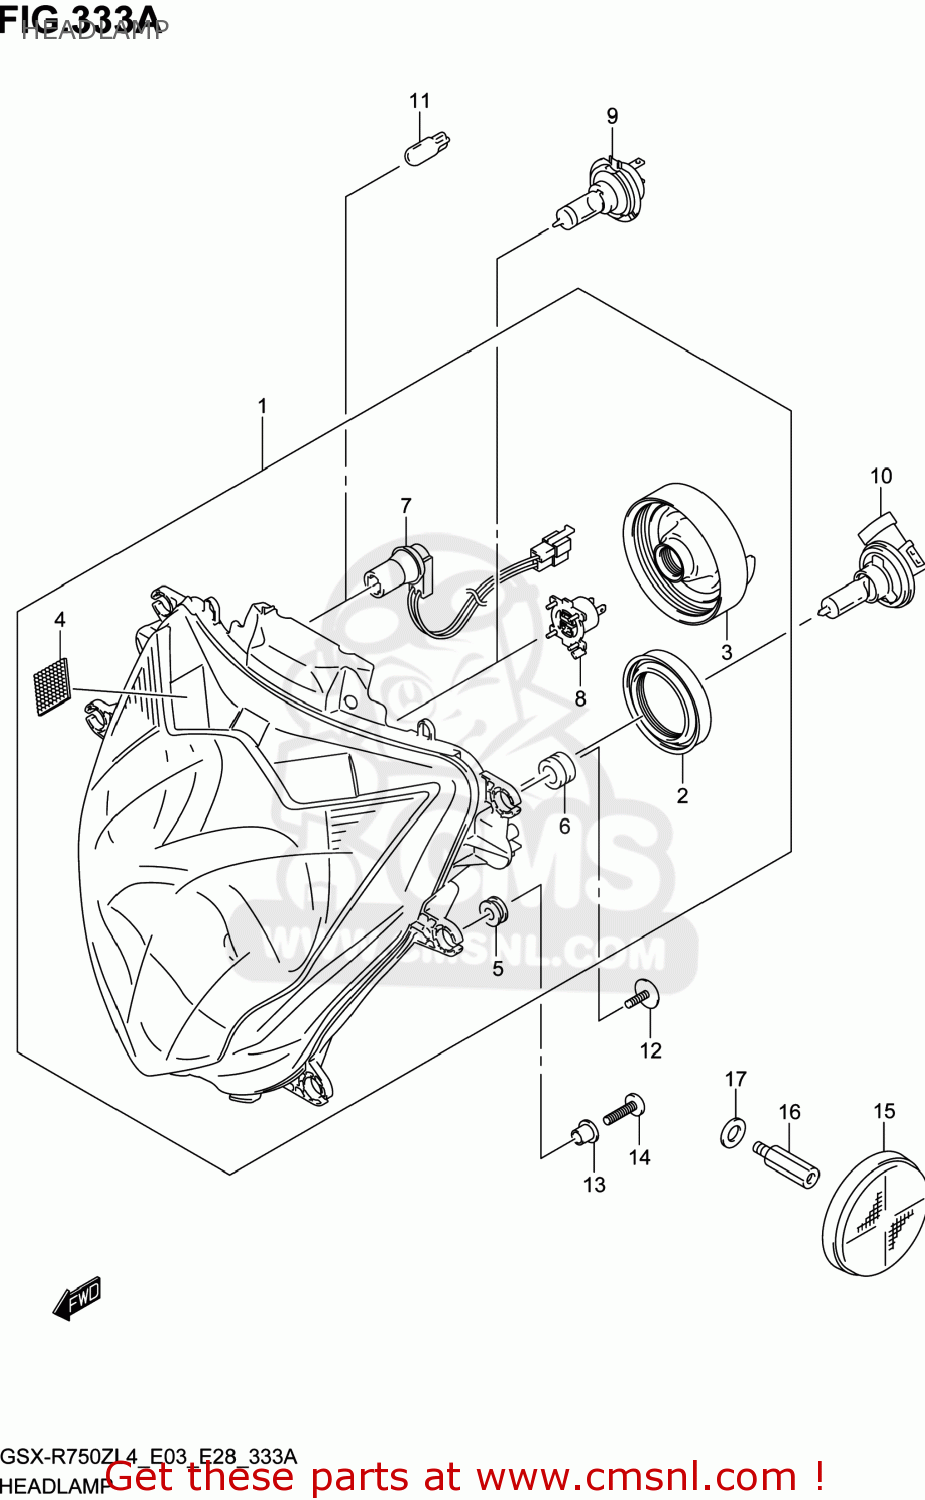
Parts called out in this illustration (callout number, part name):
1	HEADLAMP ASSY
2	COVER,SOCKET
3	COVER,SOCKET
4	FASTENER
5	CUSHION
6	CUSHION
7	CORD ASSY
8	ADAPTER ASSY
9	BULB(12V65W,H9)
10	BULB(12V55W/H7/PX26D/PHILIPS)
11	BULB(12V5W)
12	SCREW(5X15)
13	WASHER
14	SCREW
15	REFLEX REFLECTOR ASSY,FR SIDE
16	BOLT
17	WASHER(8.5X18X1)
